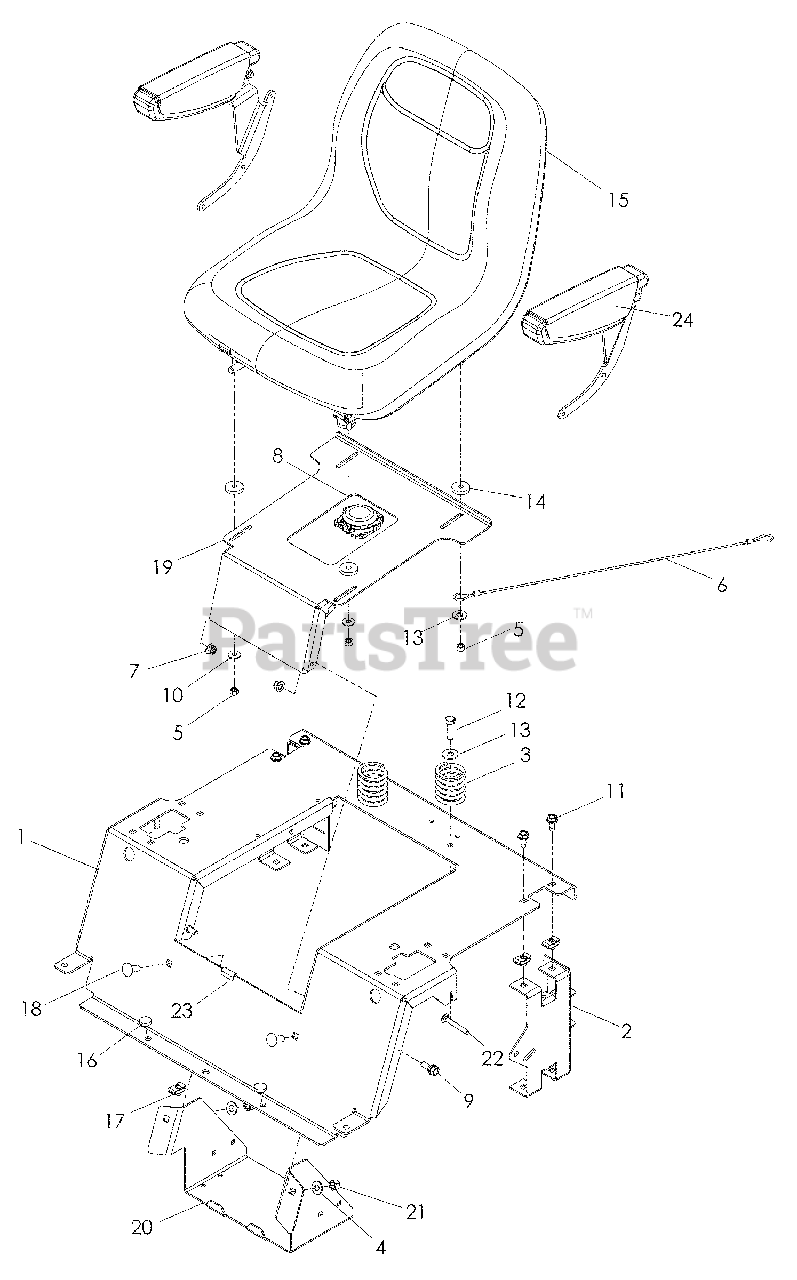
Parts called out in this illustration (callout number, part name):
1	SUPPORT, SEAT
2	SUPPORT, REAR SEAT
3	SPRING, SEAT
4	WASHER 3/8 SAE FLAT
5	NUT 5/16-18 HEX NYLOC
6	LANYARD, SEAT
7	NUT 5/16-18 FLANGE NYLOC
8	SWITCH, SEAT
9	BOLT 5/16-18 HEX HD SHLDR
10	WASHER 5/16 STD FLAT
11	BOLT 5/16-18 x ¾ THD FRM
12	HCS 3/8-16 x 1¼
13	WASHER 3/8 FLAT STD
14	WASHER, NYLON
16	GROMMET, BUMPER
17	RETAINER, U TYPE
18	RHSNB 3/8-16 x 1
19	PAN, SEAT
20	BOX, BATTERY
21	NUT 3/8-16 HEX NYLOC
22	RHSNB 5/16-18 x 2½
24	KIT, ARMREST w/FASTNRS
25	MOUNT, SPRING SEAT
